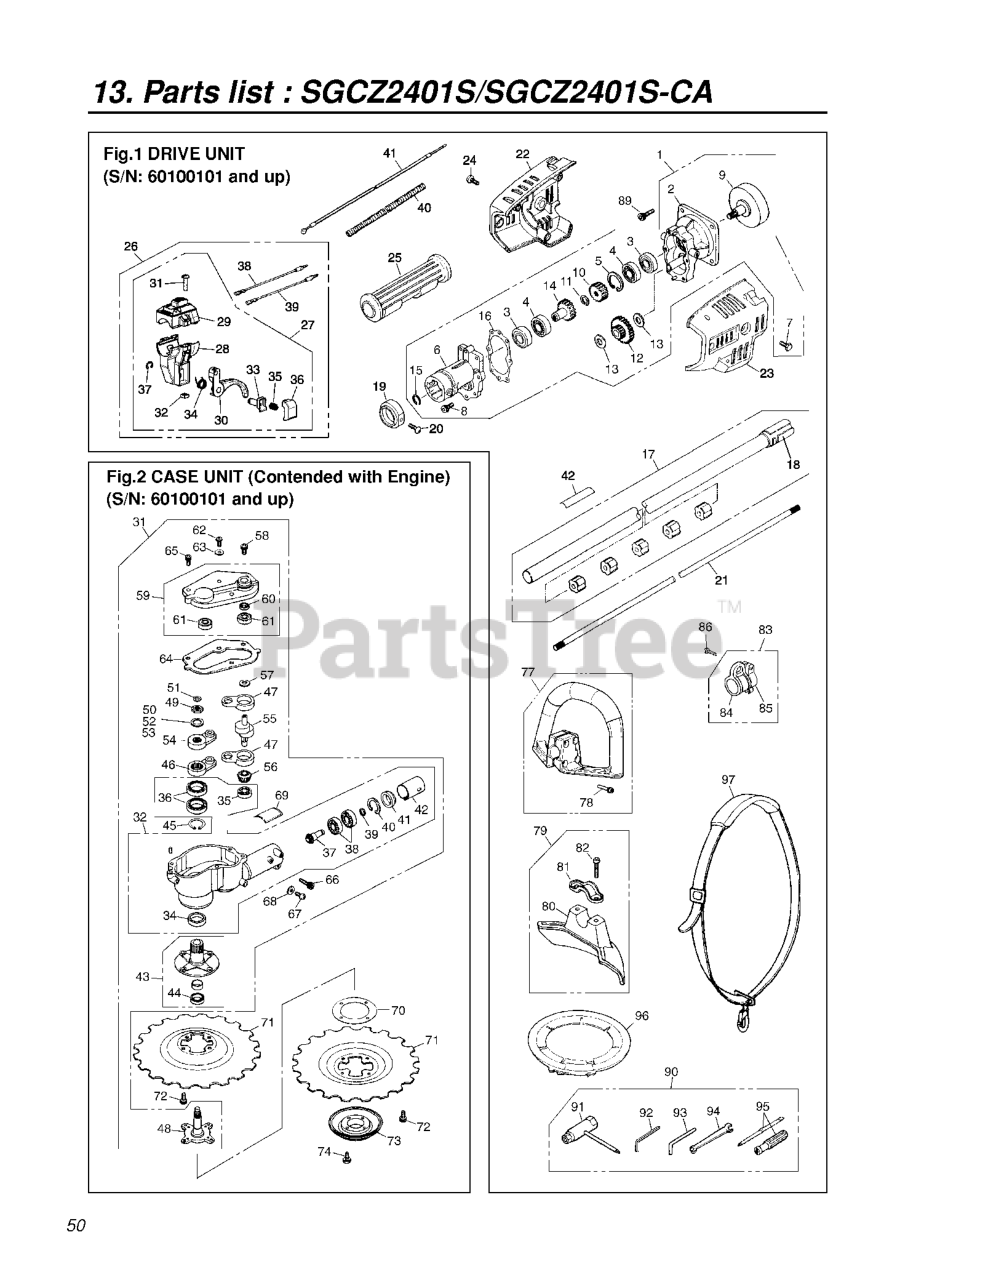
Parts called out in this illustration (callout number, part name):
1	MISSION ASSEMBLY
2	CASE,REAR COMP(RPLS 3805-11101
3	BEARING
8	BOLT
15	RING
17	PIPE COMP (RPLS 380512100)
23	COVER(L)
26	LEVER COMP (RPLS 8488R20343)
27	LEVER (FLEX. LEVER)(RPLS -13)
29	COVER COMP (RPLS 611014410-02)
38	CORD (A), BLACK
39	CORD (B), RED
41	CABLE COMP
77	HANDLE ASSY. (RPLS T319514001)
79	GUARD ASSY (RPLS 3565-24000)
83	HANGER COMP.
84	HANGER
93	Wrench Tool
96	COVER
97	STRAP ASSY
A31	CUTTERCASE ASSEMBLY
A32	CUTTERCASE (R-98100&380598100)
A35	BEARING (RPL 06000-00608)
A40	RING,SNAP M26x1.2 RP-318013340
A43	SHAFT, OUTER-C
A45	RING, SNAP, M20 x 1.2
A47	CONROD (RPLS 380513431-32)
A48	SHAFT.INNER
A50	SHIM
A52	SHIM
A53	SHIM
A55	CRANKSHAFT
A57	WASHER, M8 x 1.2
A59	COVER COMP
A61	BEARING (RPL 06000-00608)
A63	WASHER, M6 x .8
A65	BOLT, M5 x 20
A68	WASHER
A71	SGC BLADE KIT (2 BLADES/SET)
A72	BOLT, M6 x 8
A73	STABILIZER
